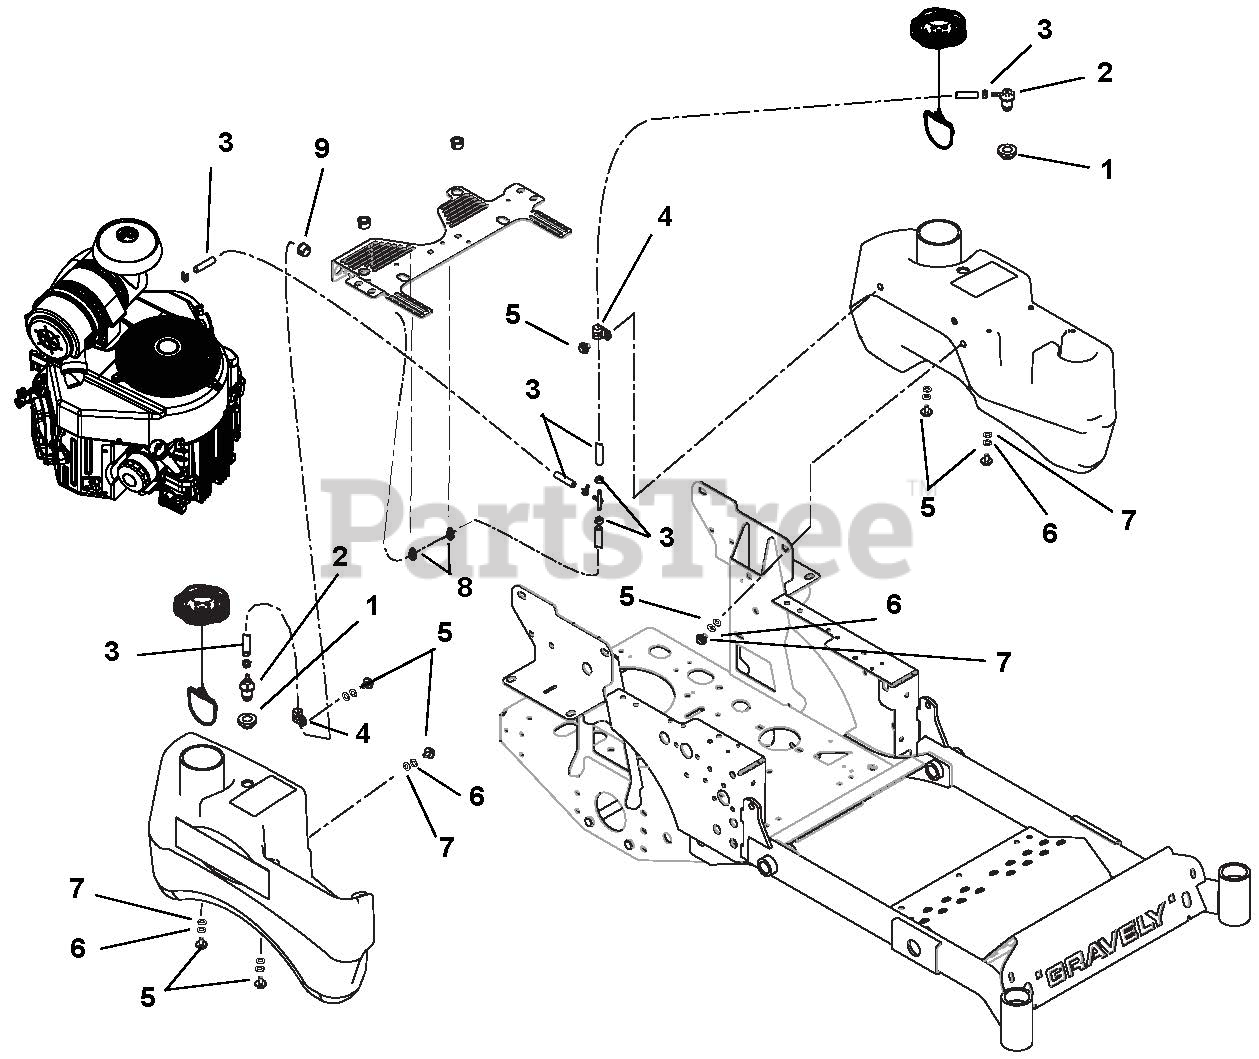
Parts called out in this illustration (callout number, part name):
1	Grommet, 2-way
2	Valve, 2-way
3	CP34, Fuel Line Assembly
5	Bolt, .31-18 x .62
6	Washer, Locking .31 x .078 Regular
7	Washer, Flat Steel .38 x .875 x .083
8	Clip, Routing
9	Bushing, Snap
